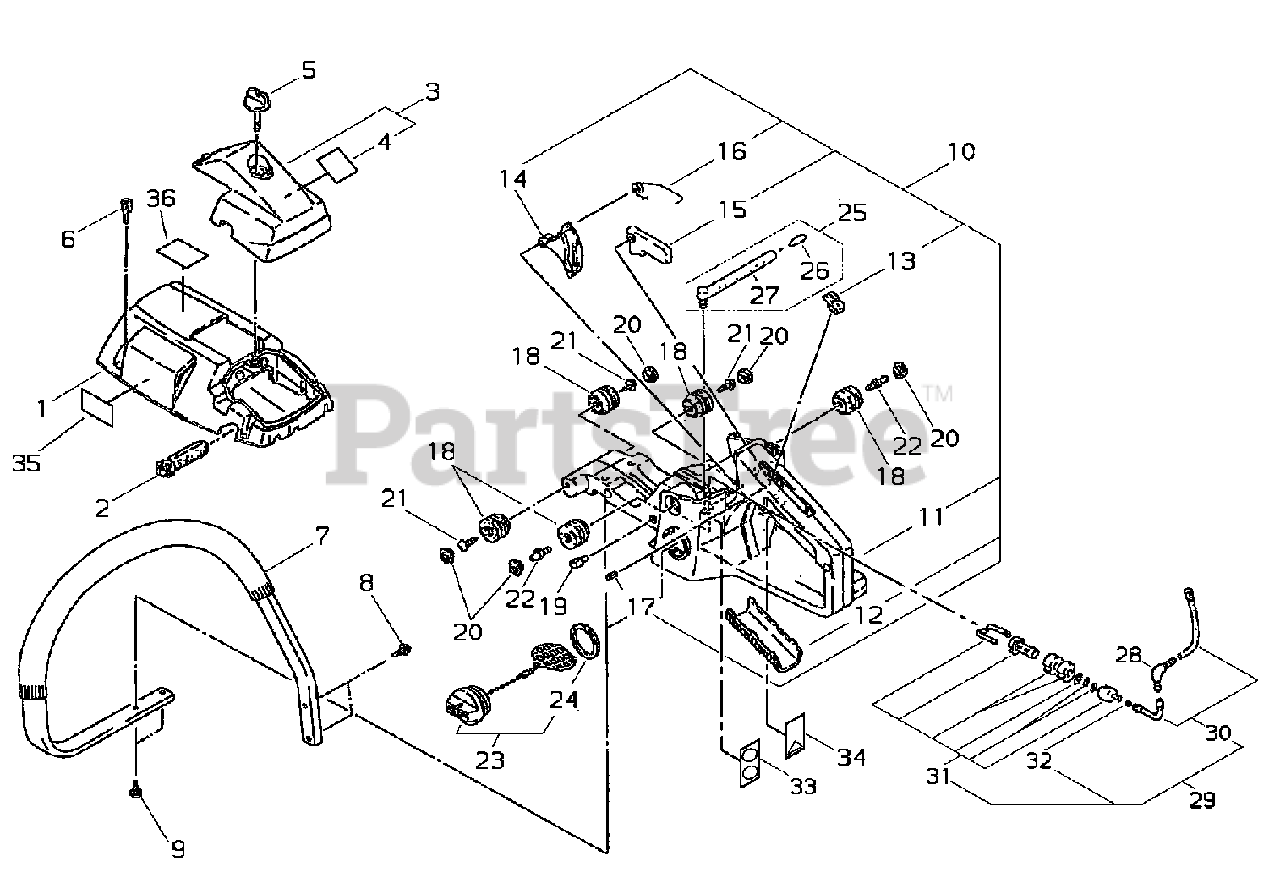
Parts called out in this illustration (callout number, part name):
1	COVER, ENGINE
2	GROMMET
3	COVER ASSY, AIR FILTER
4	LABEL, CAUTION K
5	THUMBSCREW
6	BOLT M4×16
7	HANDLE, FRONT
8	BOLT 5×21
9	BOLT 5×17
10	HANDLE ASSY, REAR
11	HANDLE, REAR
12	GRIP
13	STOPPER, SLIDE
14	TRIGGER, THROTTLE
15	LOCKOUT, THROTTLE
16	SPRING, TORSION
17	PIN, SPRING Ø4×25 MM
18	CUSHION
19	SUPPORT
20	CAP, CUSHION
21	BOLT M5
22	BOLT M5
23	CAP ASSY, FUEL
24	GASKET, CAP
25	VENT ASSY
26	VENT ASSY
27	PIPE, FUEL VENT
28	CONNECTOR
29	PIPE ASSY, FUEL
30	PIPE, FUEL
31	FILTER, FUEL
32	CLIP Ø6
33	LABEL, CAUTION I
34	LABEL, CAUTION H
35	LABEL, CAUTION A
36	LABEL, CAUTION
